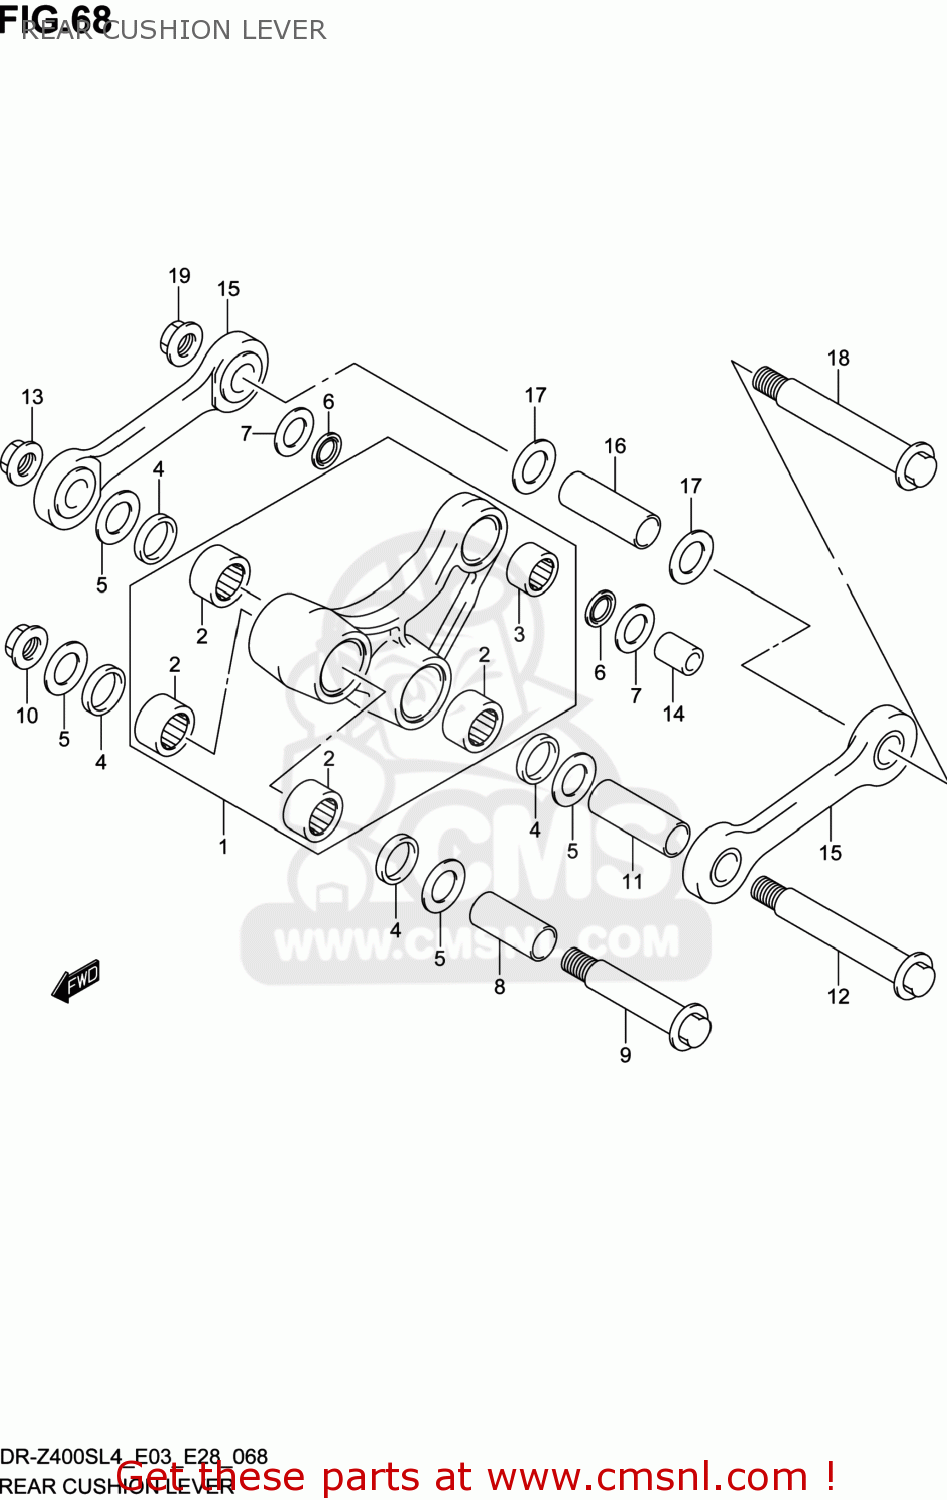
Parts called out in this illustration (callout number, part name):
1	LEVER SET,RR CUSHION
2	BEARING(20X27X15)
3	BEARING(16X22X12)
4	SEAL,CUSHION LEVER DUST
5	WASHER,THRUST SWINGARM RR
6	SEAL,OIL(16X22X2.5)
7	WASHER,THRUST LVR CUSHION RR
8	SPACER,CUSHION LEVER FR
9	BOLT,RR CUSHION LEVER FR
10	NUT
11	SPACER,RR CUSHION
12	BOLT,RR CUSHION
13	NUT
14	SPACER,RR CUSHION LEVER RR
15	ROD SET,RR CUSHION
16	SPACER,RR CUSHION
17	WASHER,THRUST SWINGARM RR
18	BOLT,RR CUSHION
19	NUT
